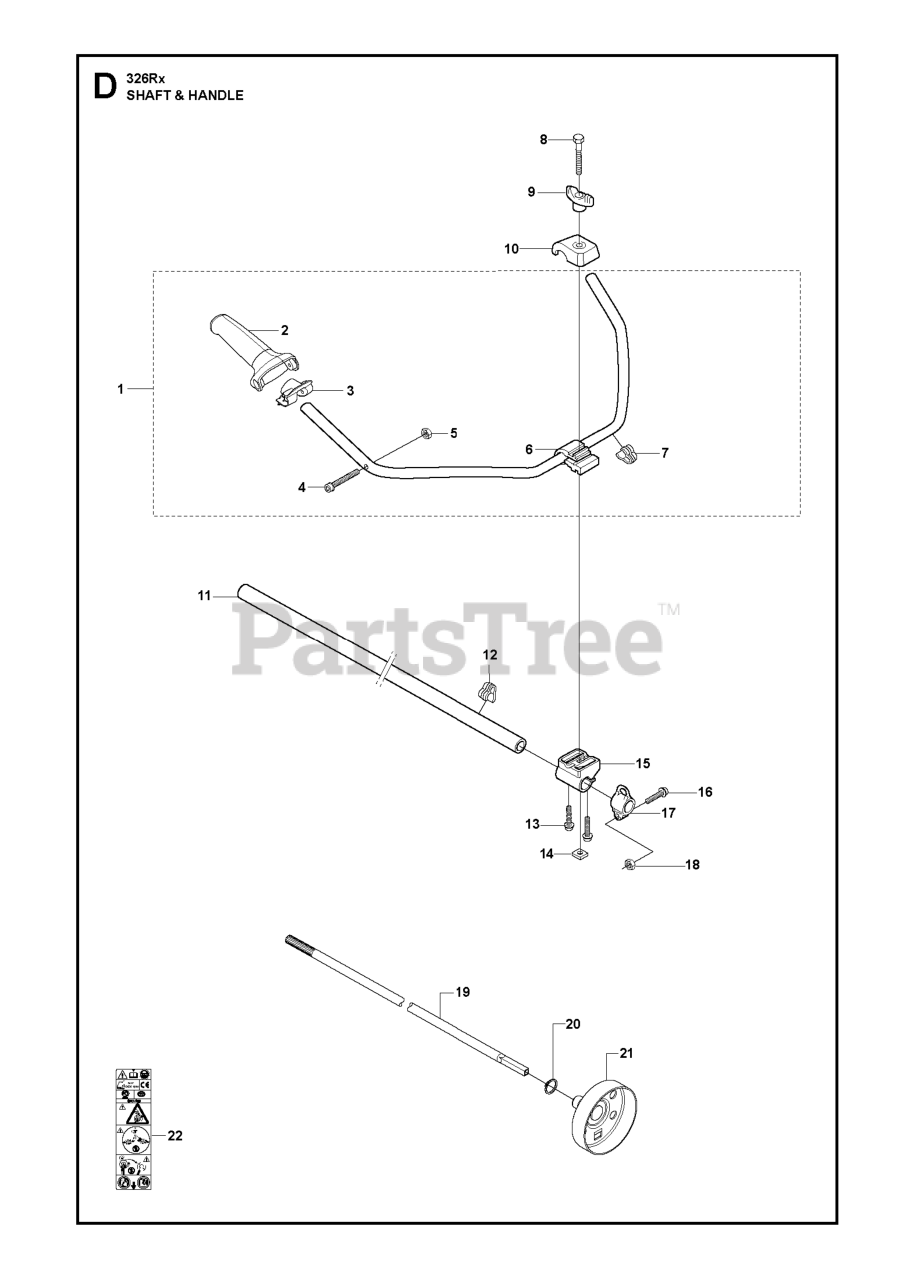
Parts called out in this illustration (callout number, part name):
6	HOLDER
11	DRIVE TUBE ASSEMBLY
16	SCREW
17	HARNESS HOLDER
19	DRIVE SHAFT
20	RETAINING RING SGA 10
21	CLUTCH DRUM
22	RP WARNING DECAL
